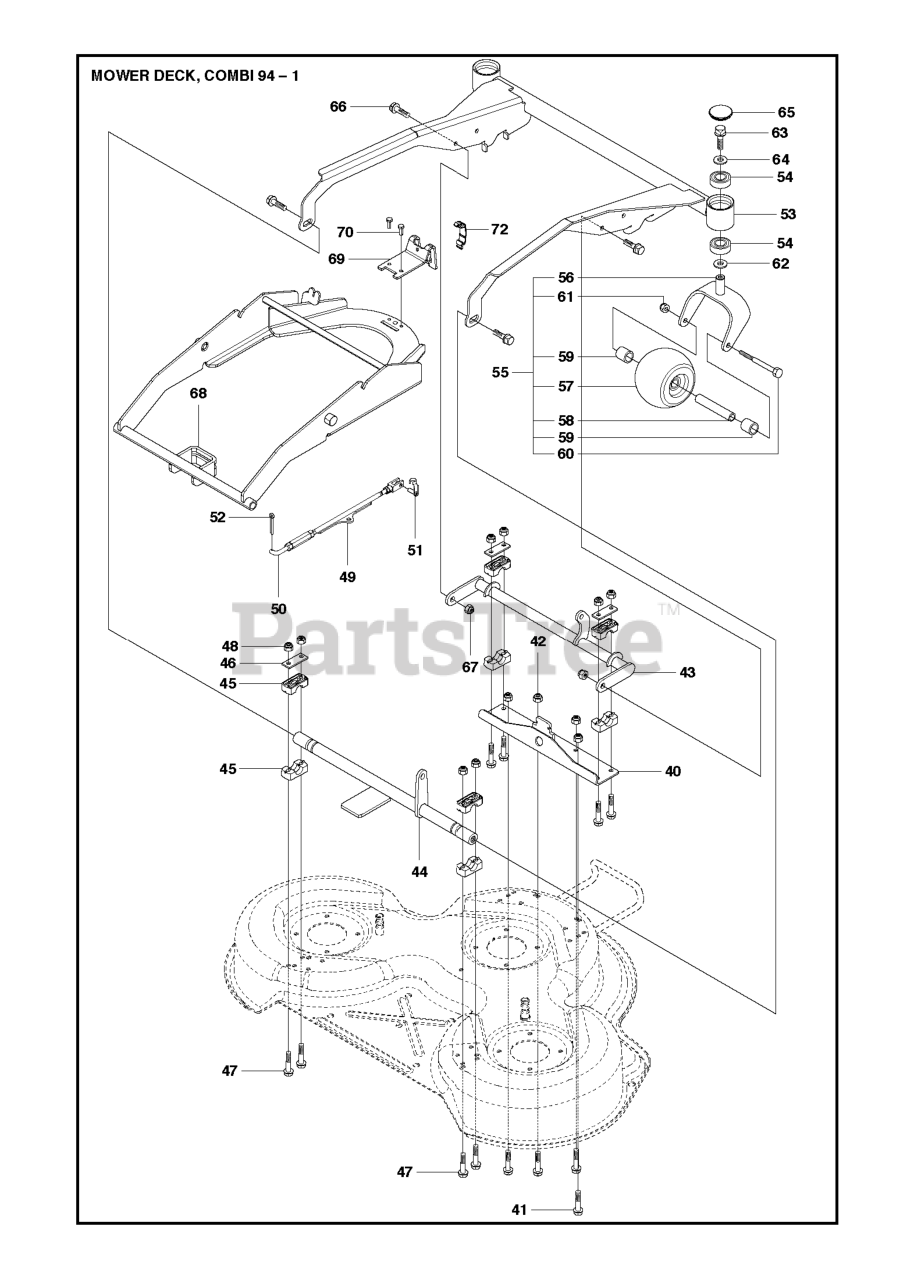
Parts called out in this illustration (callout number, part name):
1	Battery 12 Volt 25 Amp
2	BOLT.HEX.1/4.X.3/4.DICHROMATE
16	SWITCH INTERLOOK PUSH-IN
21	HARNESS.W/LIGHT SOCKET
24	BATTERY CABLE GT
25	CABLE BATTERY
26	FUSE 20AMP
27	NUT
28	CABLE GROUND
29	SWITCH.SEAT.DP W/RAMPS
30	SWITCH.IGN.DELTA.W.LGH.ROS
33	KEY.CHAIN.BLISTER.PACK.GEN.INT
41	BOLT
42	TERMINAL COVER
43	SOLENOID.W/BRASS.PLUNGER
48	ADAPTER.AMMETER
58	BUZZER
59	.WITCH.FULL BAGGER.INDICATOR
79	BULB HOLDER ASM.
81	RELAY.ASSY.T
92	HARNESS.PIGTAIL.CONSLE
93	SCREW.PLASTITE
94	MODULE.REVERSE.ROS
